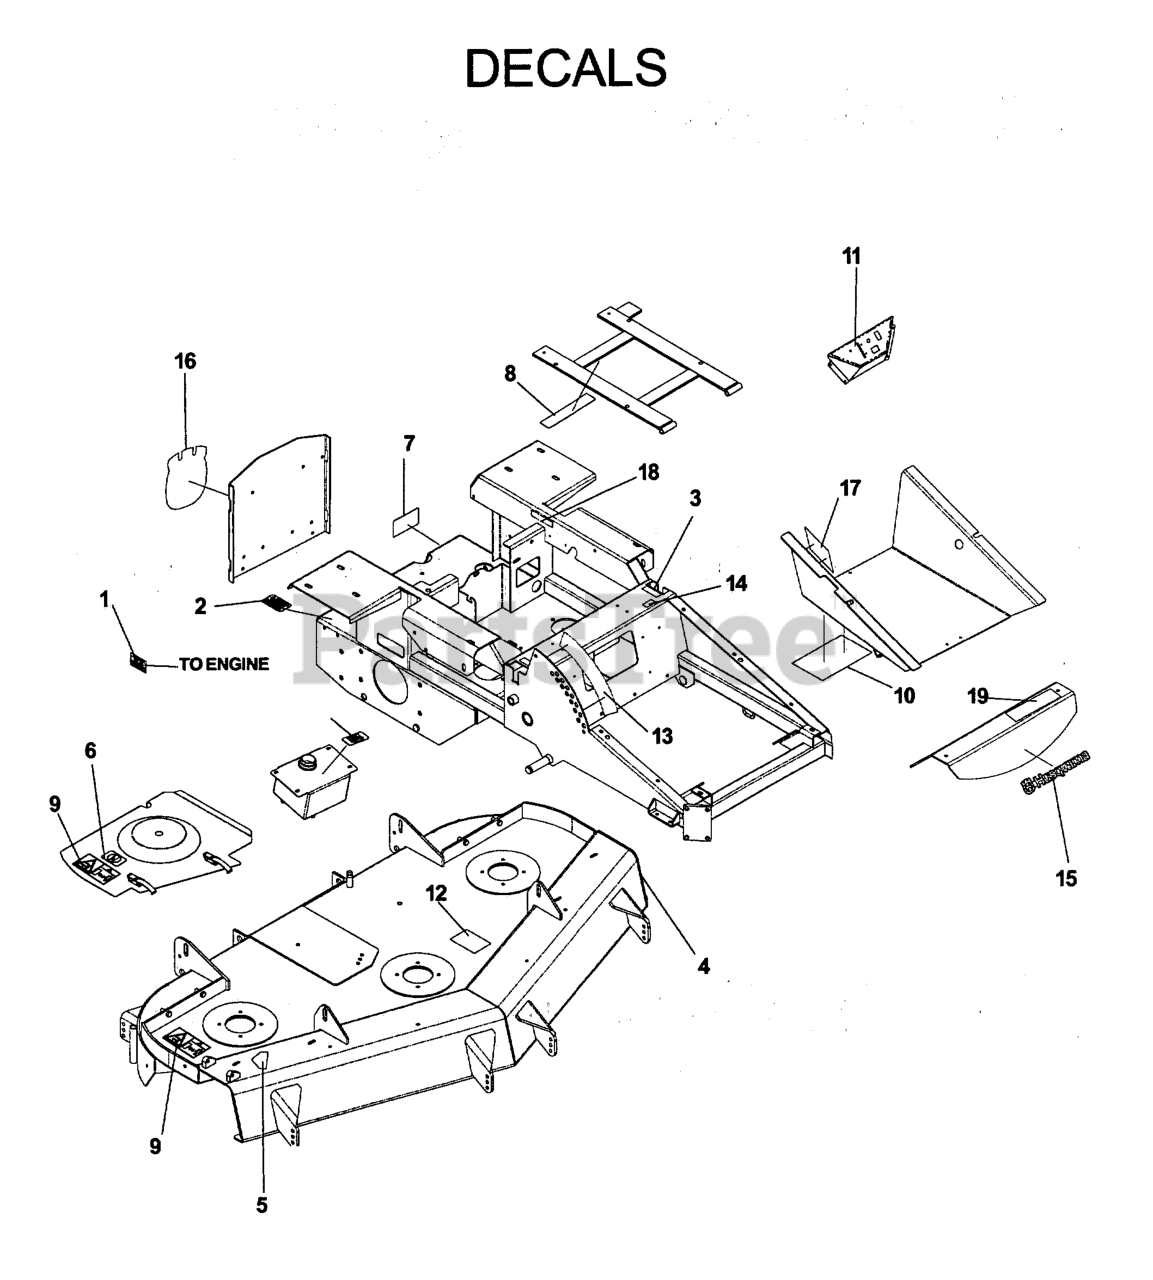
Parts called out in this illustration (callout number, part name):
1	DECAL, EXHAUST
2	DECAL, PROP. 65
3	DECAL, MOTION CONTROL
4	DECAL, NASCAR
5	DECAL, CPSC
6	DECAL, NO STEP
7	DECAL, BELT DRIVE
8	EURO DECAL-BATTERY WARNIN6
9	DECAL, EURO SEVERING
10	SERVICE DECAL
11	DECAL, CONSOLE
12	DECAL, BELT ROUTING
13	DECAL, HEIGHT ADJ
14	DECAL, F.S.T.
15	DECAL, HUSQ 12" BLUE
16	DECAL, CROWN H 5-1/4 SILVER
17	DECAL, WARNING
18	DECAL, RELAYS
19	DECAL, IZ4217
